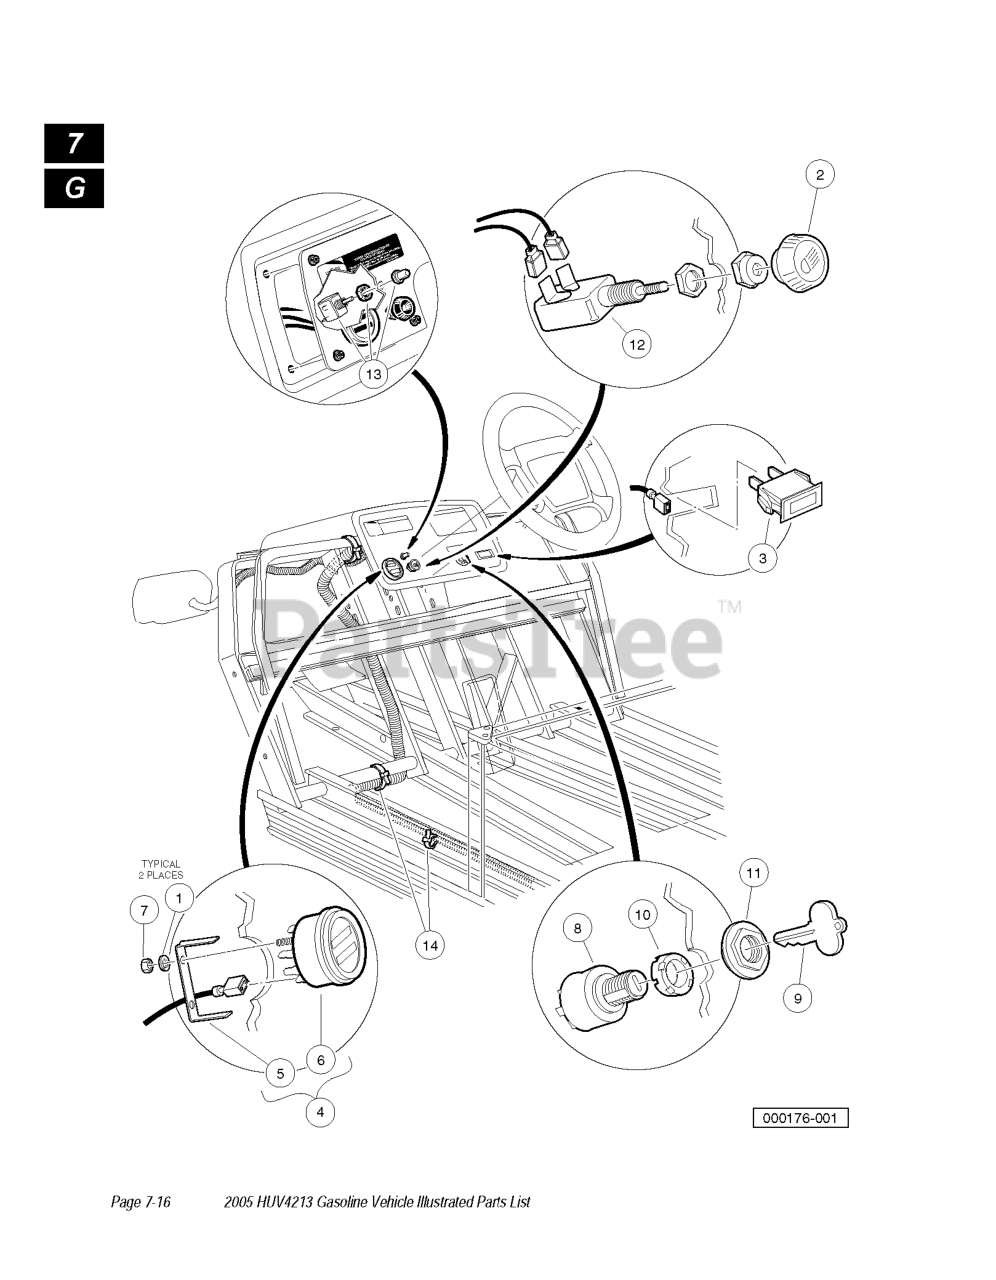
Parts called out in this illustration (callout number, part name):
2	LIGHT SWITCH KNOB
3	LIGHT, OIL
4	GAUGE,FUEL/HOUR W/BKT,UTL
7	NUT, M4-.7
8	KEY SWITCH 12V KEY START
10	SPACER, KEYSWITCH
11	NUT, KEYSWITCH
12	SWITCH, LIGHT
14	TIE WRAP, 8" NYLON
